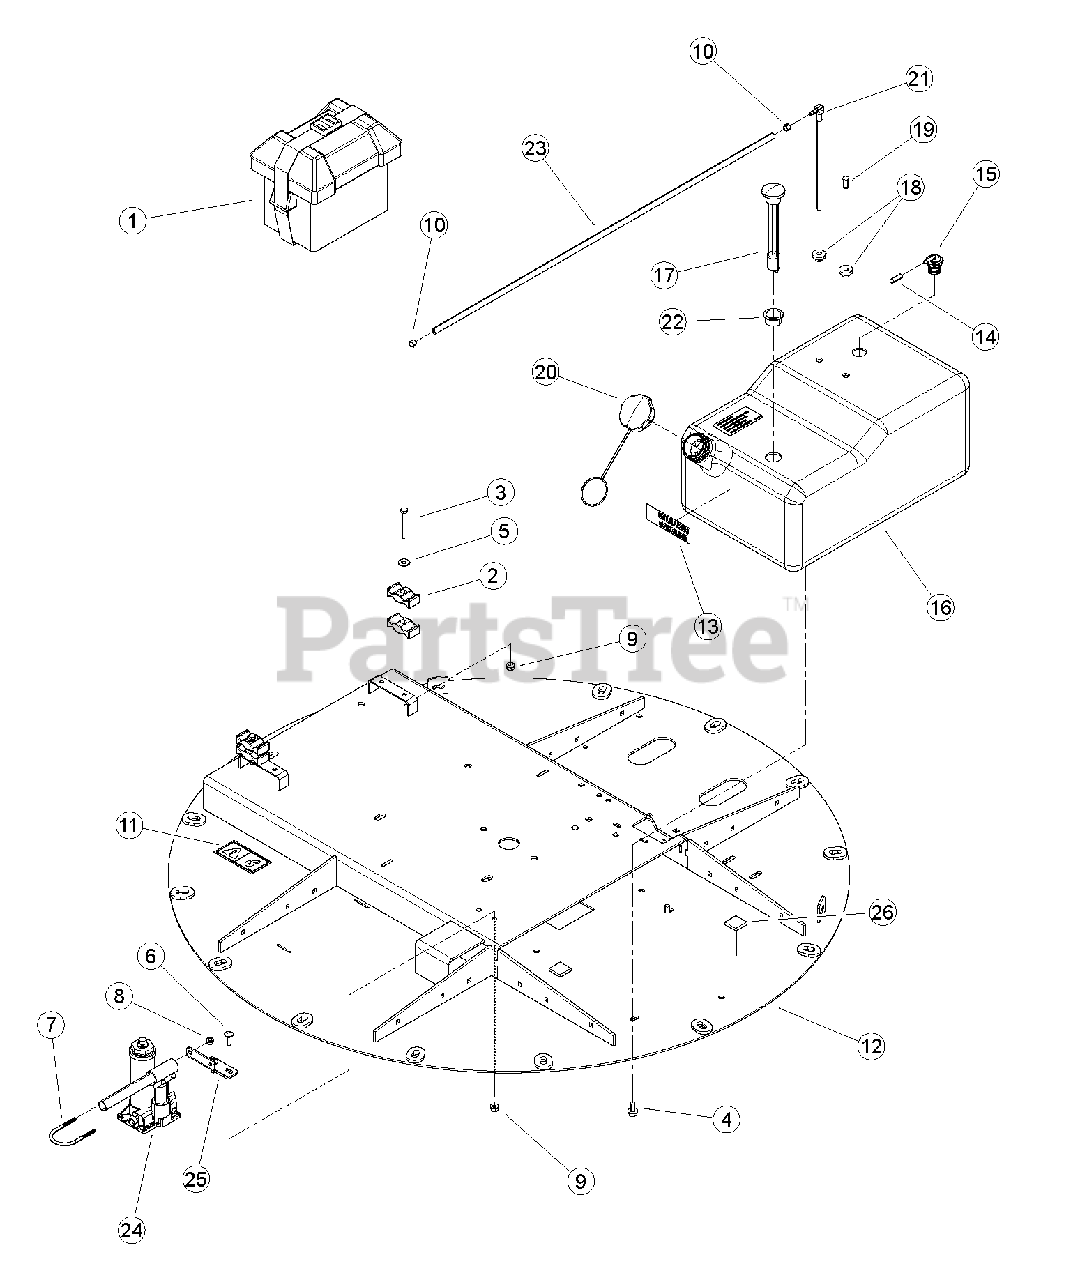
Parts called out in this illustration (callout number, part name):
1	BOX, SMALL BATTERY
2	CLAMP, PLASTIC HOSE
3	BOLT 5/16 X 2-1/2 G5 HX CAP ZP
4	BOLT, 3/8 X 3/4 FLANGE NC
5	WASHER, 5/16" FLAT ZP
6	BOLT, 5/16" X 1" GR5 CRG ZP
7	U-BOLT, 1/4 X 1-1/2 PIPE
8	NUT, 1/4-20 NYLOCK-FLANGE
9	NUT, 5/16-18 NYLOCK-FLANGE
10	CLAMP, 15/32 SPRING
11	DECAL, LOCK
12	WELDMENT, CHIPPER BASE
13	DECAL, UNLEADED GASOLINE
14	CAP, EPDM BLACK .223 ID X 1.0 LG X .06 WALL
15	VALVE, ROLL OVER
16	TANK, ROTOMOLDED FUEL
17	GAUGE, FUEL LEVEL KELCH 100
18	GROMMET, TANK FITTING
19	PLUG, TANK VENT
20	CAP, FUEL TANK VENTED
21	FITTING, TANK FUEL PICK-UP TUBE
22	GROMMET, KELCH 100 GAUGE
23	HOSE, 38" FUEL LINE
24	JACK, HYDRAULIC 2 TON
25	PLATE, JACK MOUNT
26	PAD, FOAM FUEL TANK DAMPER
